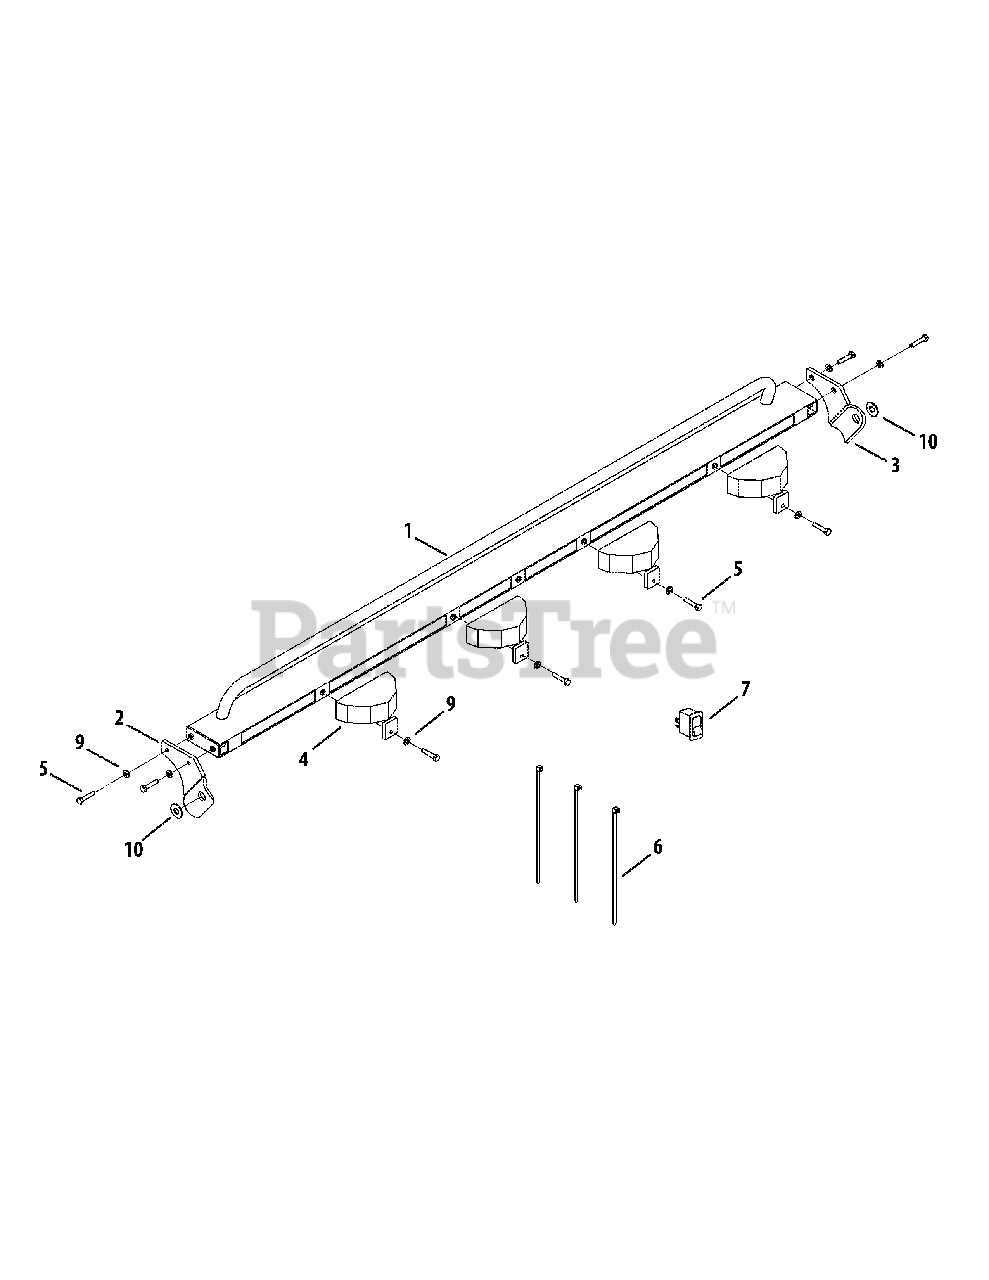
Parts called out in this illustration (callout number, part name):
1	Main Support
2	Mounting Bracket - LH
3	Mounting Bracket - RH
4	Lamp, Adjustable
5	Bolt, M6 x 30
7	Switch, Headlight Rocker
9	Washer, Flat, .271 x .630 x .065
10	Washer, Flat, .450 x 1.250 x .164
